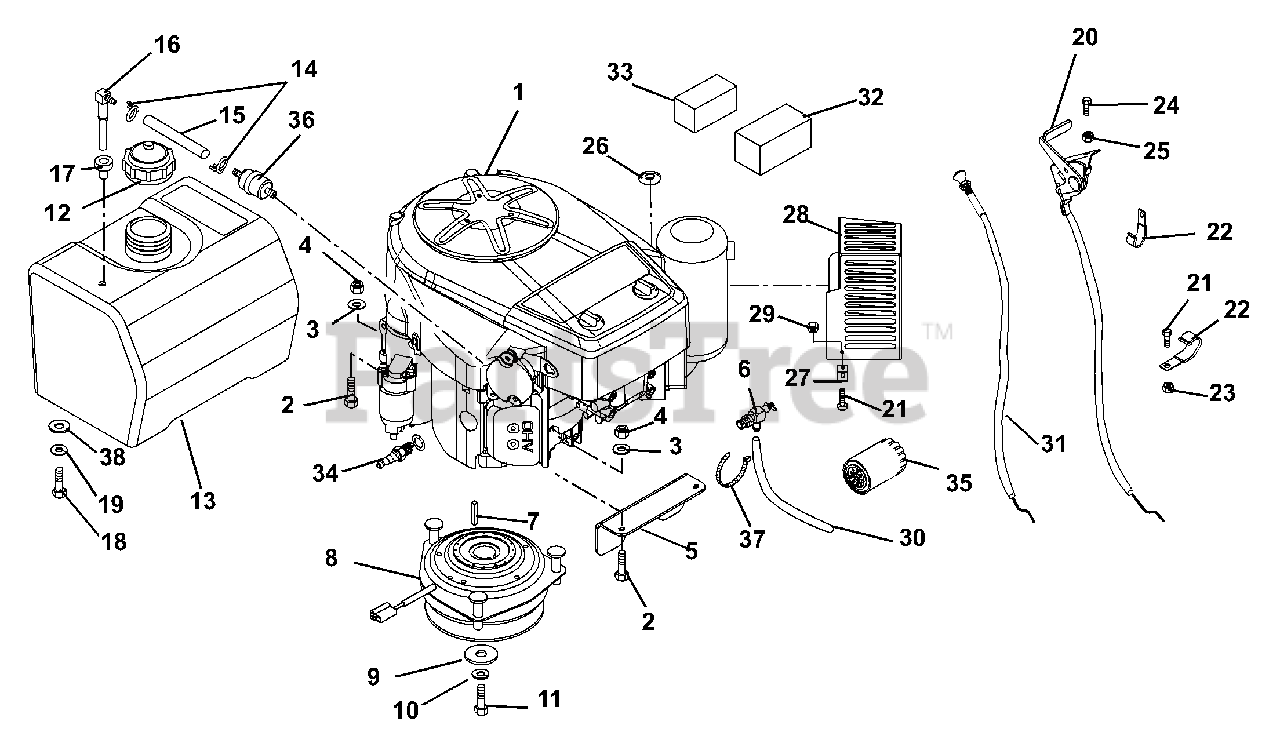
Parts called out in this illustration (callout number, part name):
1	19 HP KAWI PRO WALK ENGINE
2	@BLT-HEX .31-18X1.75 GR5 YWZC
3	@WSHR-LK .31X.078 REG YWZC
4	@NUT-HEX .31-18 YWZC
5	BRACKET, CLUTCH
6	VALVE, OIL DRAIN
7	KEY-SQ .25 X 1.25 X .25 SAE
8	CLUTCH,ELECTRIC PTO
9	WSHR-FL-STL .469X2.00X.25 YWZC
10	@WSHR-LK .44X.109 REG YWZC
11	BLT-HEX .44-20X3.00 GR5 YWZC
12	CAP - FUEL
13	TANK - FUEL
14	CLAMP-HOSE WIRE .490/.510X.116
15	GAS LINE-BULK 1/4" I.D.
16	FITTING, TANK
17	GROMMET, DAPCO VITON #12240
18	@BLT-HEX .38-16X.75 GR5 YWZC
19	@WSHR-LK .38X.094 REG YWZC
20	CABLE - THROTTLE W/LINER
21	@BLT-HEX .31-18X.75 GR5 YWZC
22	J-CLAMP
23	@NUT-LK-NYL .312-18 YWZC
24	@SCR-MCH 10-24X.75 HWH YWZC
25	@NUT-LK-NYL 10-24 W/INSRT YWZC
26	WSHR-FL-STL .328X.87X.179 YWZC
27	BRACKET, MUFFLER GUARD
28	GUARD, MUFFLER
29	@NUT-LK-CTR .31-18 YWZC
30	TUBE, OIL DRAIN 8" CLEAR VINYL
31	CONTROL,CHOKE
32	AIR FLTR,PAPER KAWASAKI
33	AIR FLTR,FOAM KAW
34	PLUG, SPARK
35	FILTER,OIL - KAW
36	FUEL FILTER - KAWASAKI
37	CABLE TIE LG 5-1/2
38	@WSHR-FL-STL.406X.812X.065 YWZ
